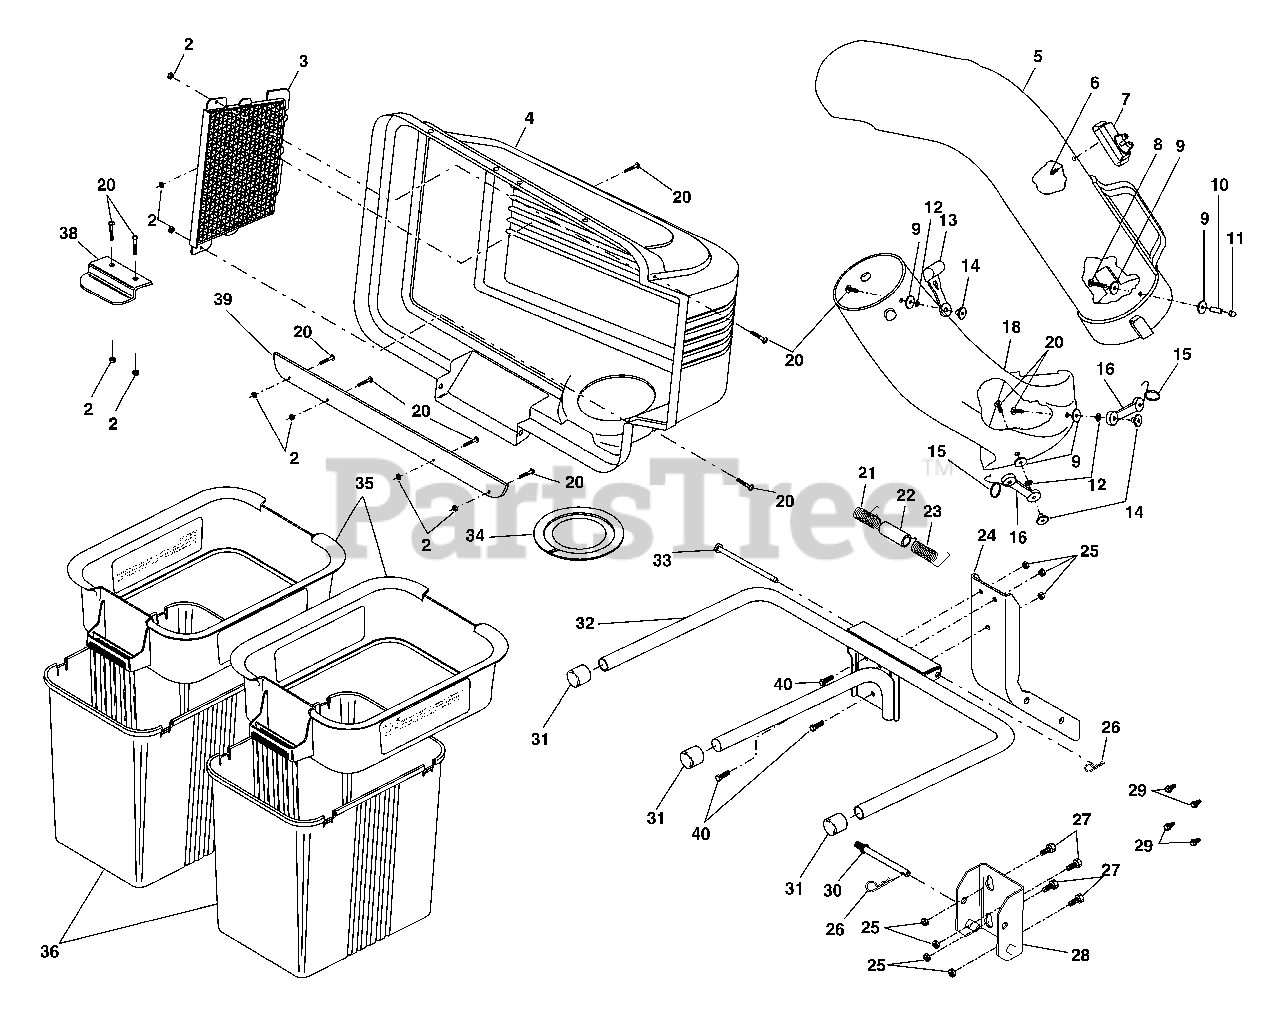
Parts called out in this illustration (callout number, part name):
2	Nut, Crownlock #10-24
3	Screen, Cover
4	Cover Asm.
5	Chute, Upper
6	Screw, Special #10-14x1/2
7	Dump Bag Indicator
8	Screw, #10-24 x 1-1/8
9	Washer 3/16x3/4x16 Ga.
10	Spacer, Split
11	Nut, Acorn #10-24
12	Washer, lock
13	Latch, Chute
14	Nut, Weld
15	Latch, Hook
16	Rubber, Latch
18	Chute, Lower
20	Screw #10-24 x 5/8
21	Spring, Cover L.H. (black)
22	Spacer, Cover
23	Spring, Cover R.H. (gray)
24	Post, Support
25	Locknut 5/16 x 18
26	Spring, Retainer
27	Bolt, Hex 5/16-18 x 3/4
28	Bracket, Mounting
29	Shoulder Bolt
30	Pin, Support Post
31	Plug, Tubing End
32	Bagger, Frame
33	Pin, Hinge
34	Gasket, Cover
35	Container, Top
36	Container, Bottom
38	Latch Handle, Cover
39	Strip, Reinforcement
40	Carriage Bolt 5/16-18 x 3/4
